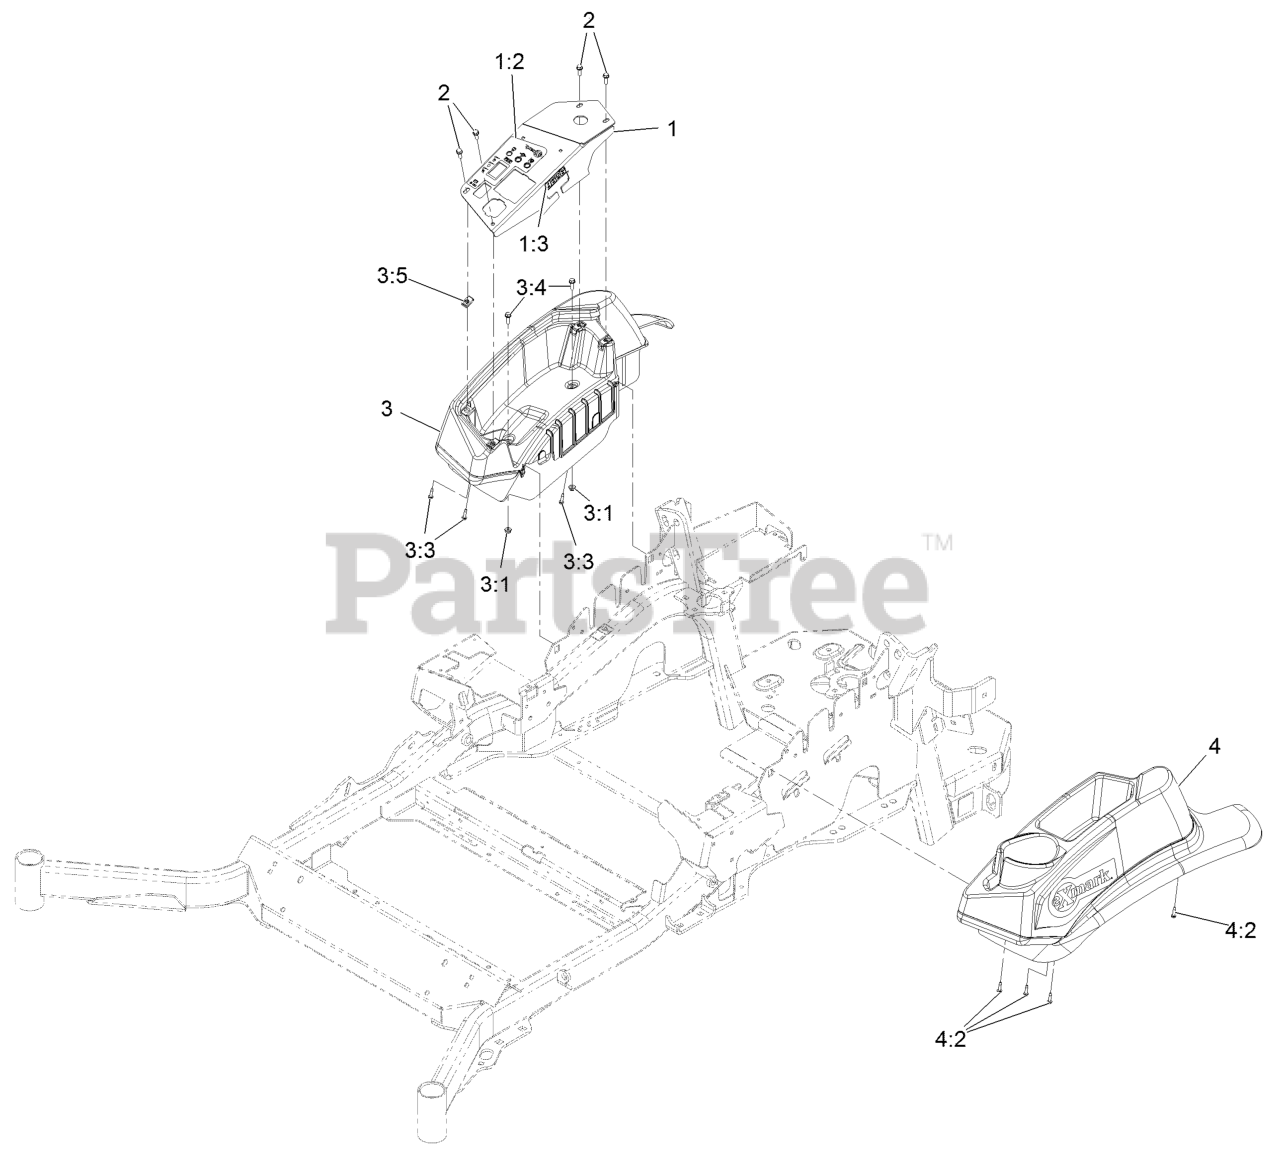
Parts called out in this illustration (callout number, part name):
1	CONTROL PANEL W/DECAL
1:2	DECAL-CONSOLE RED
1:3	DECAL-FUSES
2	SCREW-HWH
3	CONSOLE,RH NARROW ASM
3:3	SCREW,THD FORM,HWH
3:4	SCREW-HWH
3:5	Nut-Retainer-Panel 1/4-20
4	CONSOLE.LH NARROW ASM
4:2	SCREW,THD FORM,HWH
